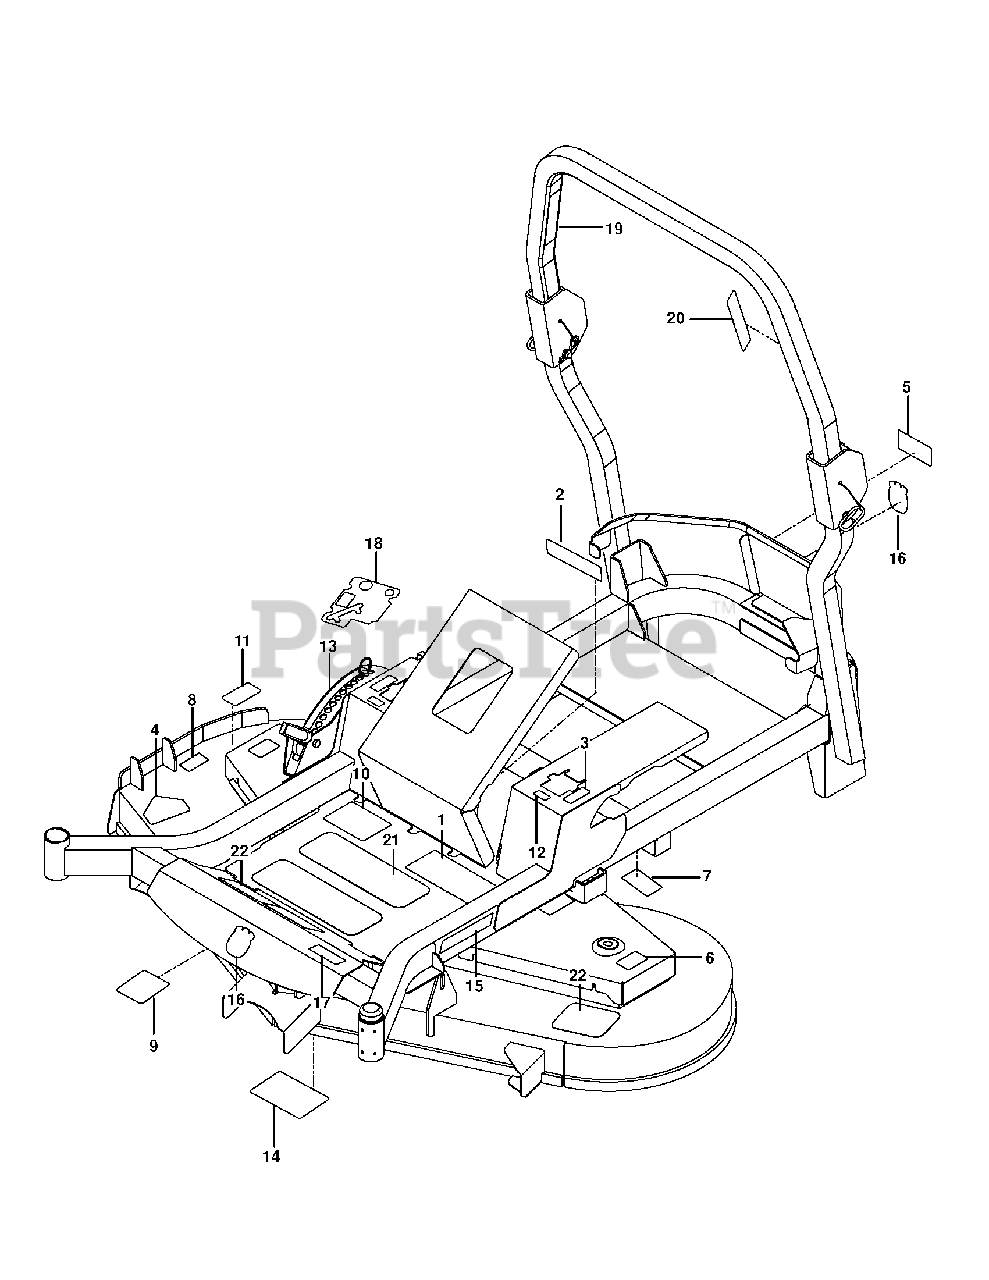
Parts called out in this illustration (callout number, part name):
1	DECAL, WARNING
2	EURO DECAL-BATTERY WARNIN6
3	DECAL, MOTION CONTROL
4	DECAL, CPSC
5	DECAL, BELT DRIVE
6	DECAL, NO STEP
7	DECAL ZTR MZT61 HUSQVARNA
8	DECAL, EURO SEVERING
9	DECAL, BELT ROUTING
10	DECAL, WARNING
11	DECAL.DECK.6MIL./DEF.SHLD.WARN
12	DECAL, F.S.T.
13	DECAL, HEIGHT ADJUST
14	DECAL, SERVICE
15	RP.DECAL.BADGE.170MM.TEXTLOGO
16	DECAL.AUGER.HUSQ.CROWN.SNOW
17	DECAL ZTR MZT61 HUSQVARNA
18	DECAL, CONSOLE HUS
19	DECAL, ROPS, WARNING
20	DECAL ROPS
21	ANTI-SKID PAD
